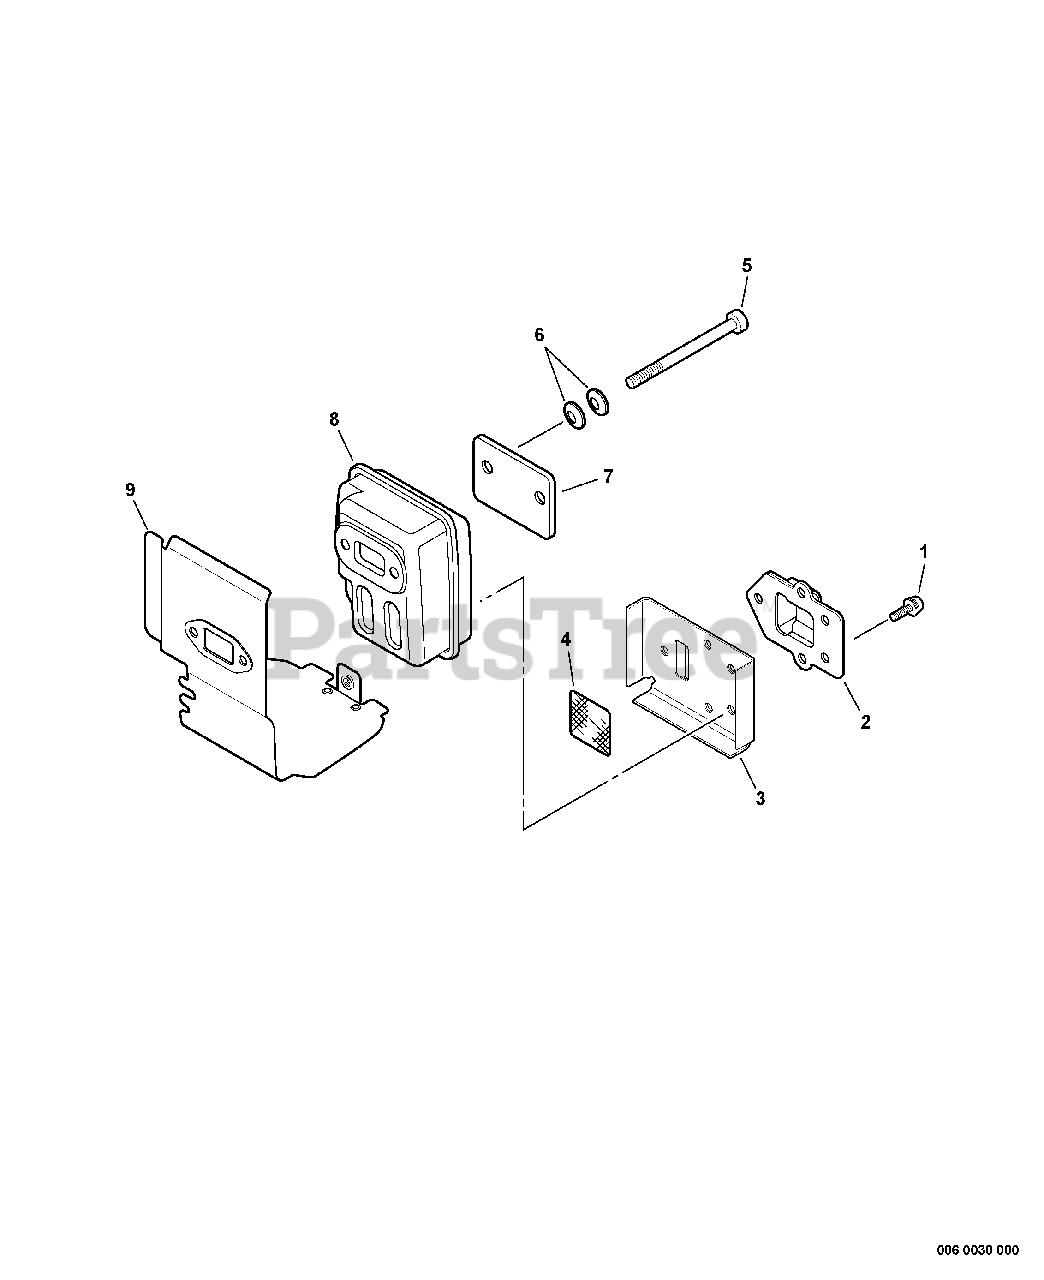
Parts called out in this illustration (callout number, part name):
1	HEAT SHIELD, EXHAUST
2	MUFFLER
3	PLATE, EYE
4	BOLT 5×55
5	CONICAL WASHER
6	SCREEN, SPARK ARRESTER
7	GASKET, EXHAUST
8	GUIDE, EXHAUST
9	SCREW 4×12
